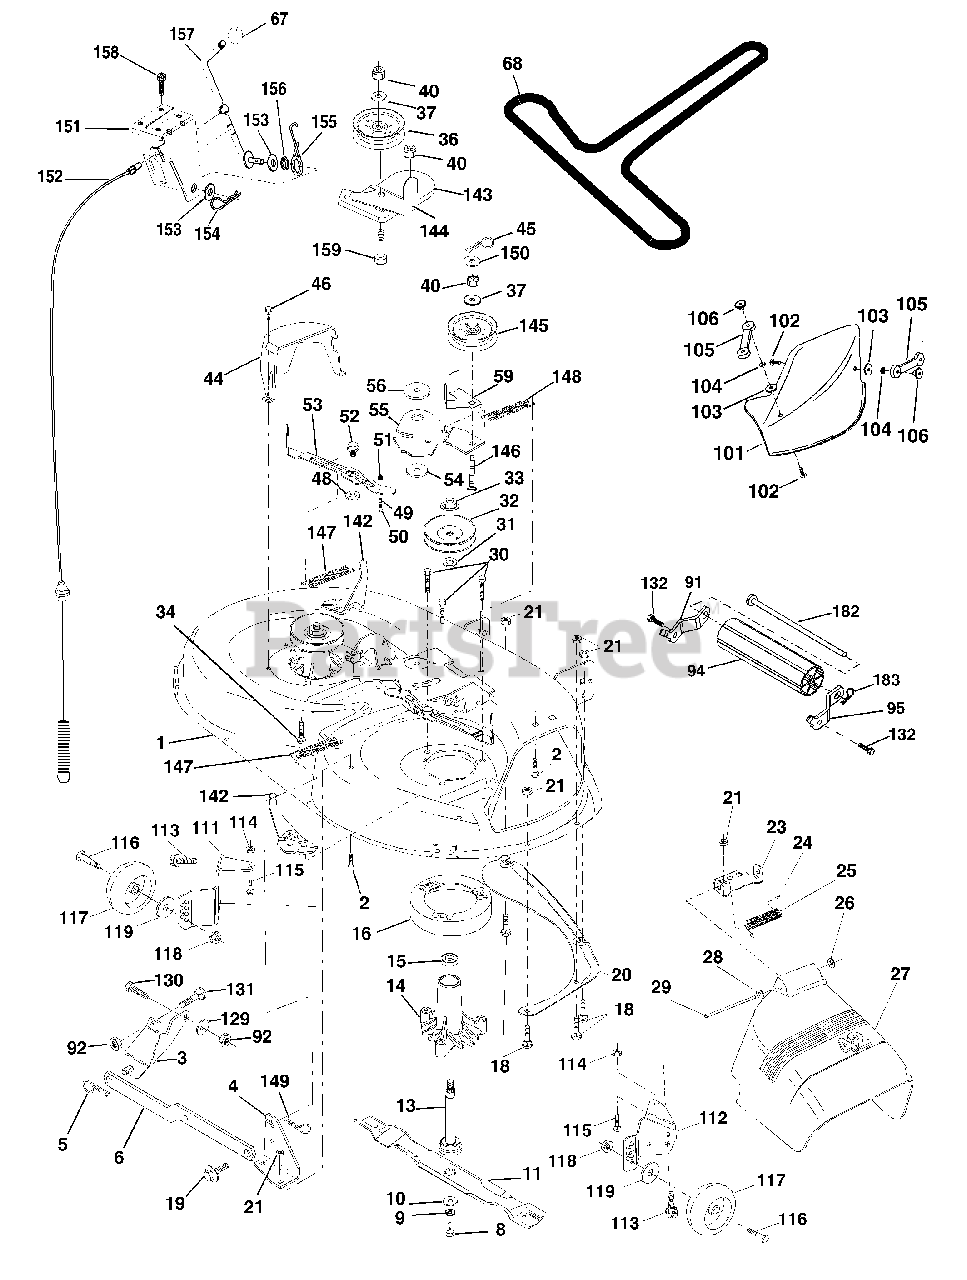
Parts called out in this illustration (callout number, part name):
1	Mower Deck Assembly, 42"
2	Bolt
3	Bracket Asm Fr. Sway Bar 3/42
4	Bracket Asm Deck 42" Sway Bar
5	Retainer Spring
6	Bar Sway Deck
8	Bolt 3/8-24 x 25 Grade 8 patched
9	Washer, Lock
10	Washer, Hardened
11	Blade, Mulching 42"
11	Blade Mower 42" Hi-Lift
13	Shaft Assembly, Mandrel, Vented
14	Housing, Mandrel, Vented
15	Bearing, Ball, Mandrel
16	Stripper, Mandrel Deck
18	Bolt, Carriage 5/16-18 x 5/8
19	Bolt, Shoulder
20	Baffle, Vortex
21	Nut
23	Bracket, Deflector Mower 42"
24	Cap, Sleeve 80 x 112 Blk Mower
25	Spring, Torsion, Deflector 2 52
26	Nut, Push Phos & Oil
27	Shield, Deflector 42" Blk
28	Washer 11/32 x 5/8 x 16 Gauge
29	Rod, Hinge 42" 6 75 W/G
30	Screw Thdrol Washer Head
31	Washer, Spacer Mower Vented
32	Pulley, Mandrel
33	Nut, Toplock 9/16 Flange
34	Bolt
36	Pulley, Idler, Flat
37	Washer 13/32 x 13/16 x 16 Gauge
40	Nut
44	Guard, Mandrel, LH
45	Retainer
46	Screw, Thdrol 1/4-20 x 5/8 T
48	Washer, Hardened
49	Roller Assembly, Cam Follower
50	Bolt, Shoulder #10-24 Grade 5
51	Locknut
52	Bolt, Shoulder 5/16-18 UNC
53	Arm Assembly, Pad, Brake
54	Washer, Hardened
55	Arm, Idler
56	Spacer, Retainer
59	Guard TUV Idler
67	Knob
68	V-Belt, 42" Mower
91	Bracket Asm. Noseroller LH
94	Roller, Nose
95	Bracket Asm. Noseroller RH
101	Mulcher Cover
102	Screw
103	Washer, Flat
104	Washer, Lock
105	Latch Assembly
106	Nut, Weld
111	Bracket, Gauge, Wheel LH
112	Bracket, Gauge, Wheel RH
113	Screw 3/8-16 x .625
114	Nut, Keps 5/16 - 18 UNC
115	Bolt, Carriage 5/16-18 x 5/8
116	Bolt, Shoulder
117	Wheel, Gauge
118	Nut Centerlock 3/8-16
119	Washer 3/8 x 7/8 x 14 Ga.
132	Screw 3/8-16 x .75
142	Arm Spring Brake Mower
143	Bracket Arm Idler 42"
144	Keeper Belt 42" Clutch Cable
145	Pulley Idler Flat
146	Bolt Carriage Idler
147	Spring Extension
148	Spring Return Idler
149	Retainer Spring Yellow
150	Washer 9/32 x 3/4 x 16 Ga.
151	Bracket Clutch Cable
152	Clutch Cable 42"
153	Washer Flat 3/8" Type B
154	Spring Retainer
155	Spring Retention LVR CLTCH CAB
156	Spacer Clutch Cable
157	Rod Clutch Cable 3/8"
158	Screw Hex Thd Cut 1/4-20 x 5/8
159	Bolt Rdhd Sqn 3/8-16 UNC x 1-3/4
182	Rod Roller Nose
183	Retainer Spring
